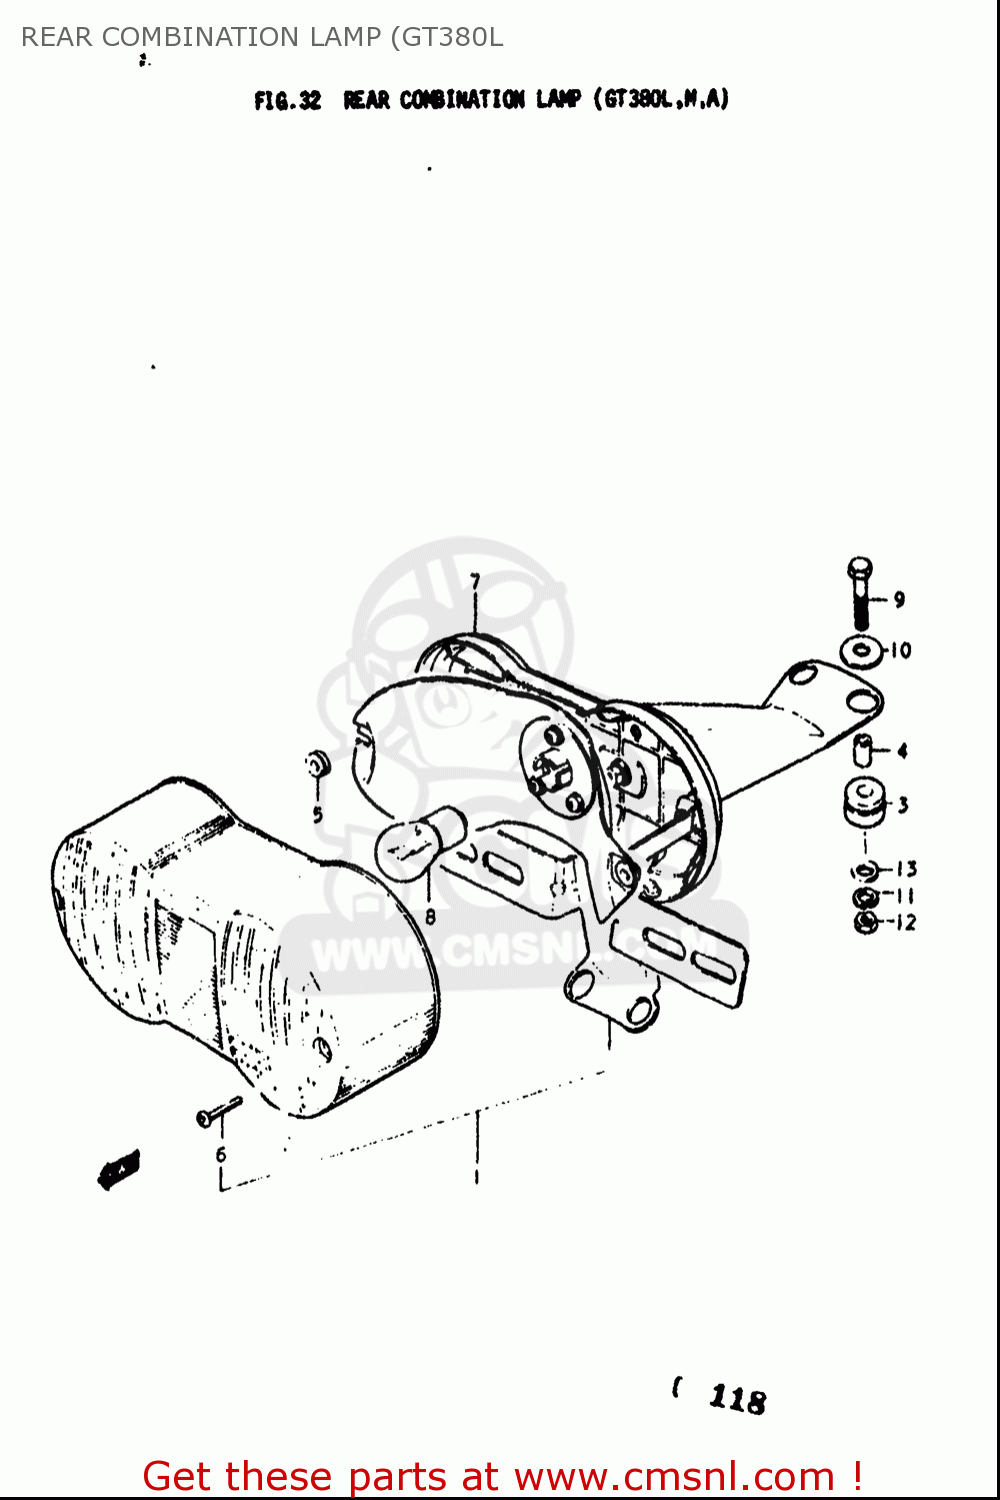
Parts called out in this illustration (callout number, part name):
2	LENS,RR COMBINATION LAMP
3	CUSHION
4	SPACER
5	CUSHION
6	SCREW
7	HOUSING,RR COMBINATION LAMP
8	BULB(12V23W)
9	BOLT
10	WASHER(6.5X20X1.6)
11	WASHER,LOCK
12	NUT
13	WASHER
